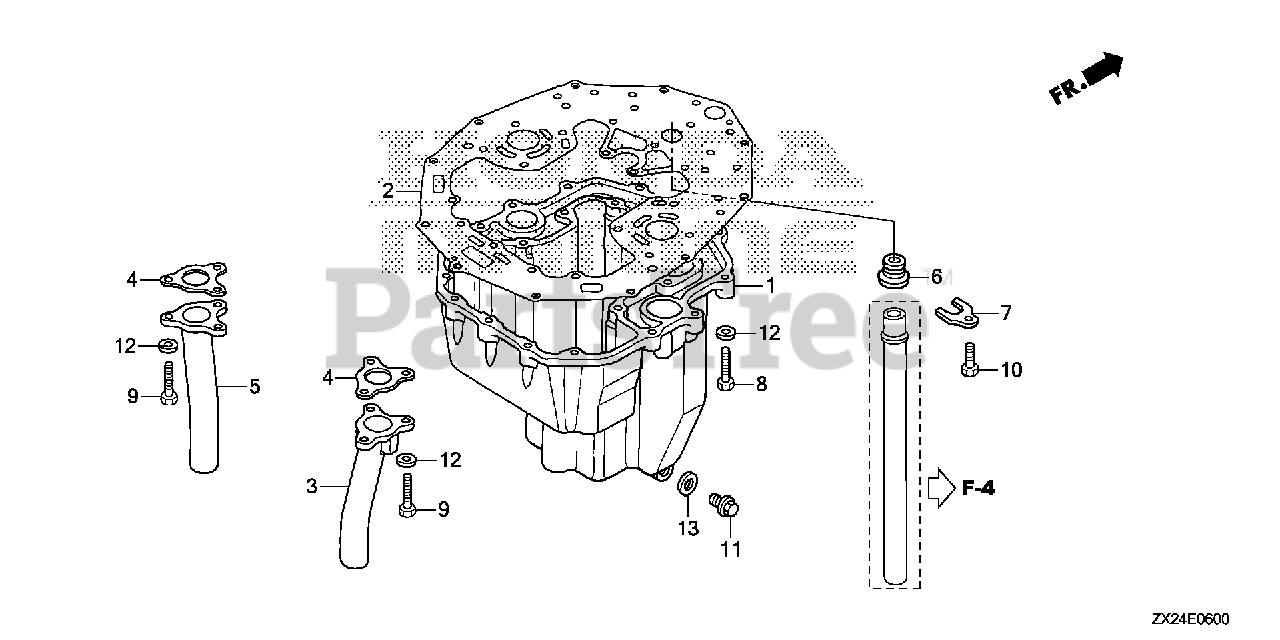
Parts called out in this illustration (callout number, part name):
1	PAN, OIL *TGRAY* (GRAY)
2	GASKET, OIL PAN
3	PIPE, R. EX.
4	GASKET, EX. PIPE
5	PIPE, L. EX.
6	GROMMET, WATER TUBE
7	PLATE, WATER TUBE
8	BOLT, HEX. (8X35)
9	BOLT, HEX. (8X28)
10	BOLT, HEX. (6X16)
11	BOLT, DRAIN PLUG
12	WASHER, PLAIN (8MM)
13	WASHER, DRAIN PLUG (12MM)
